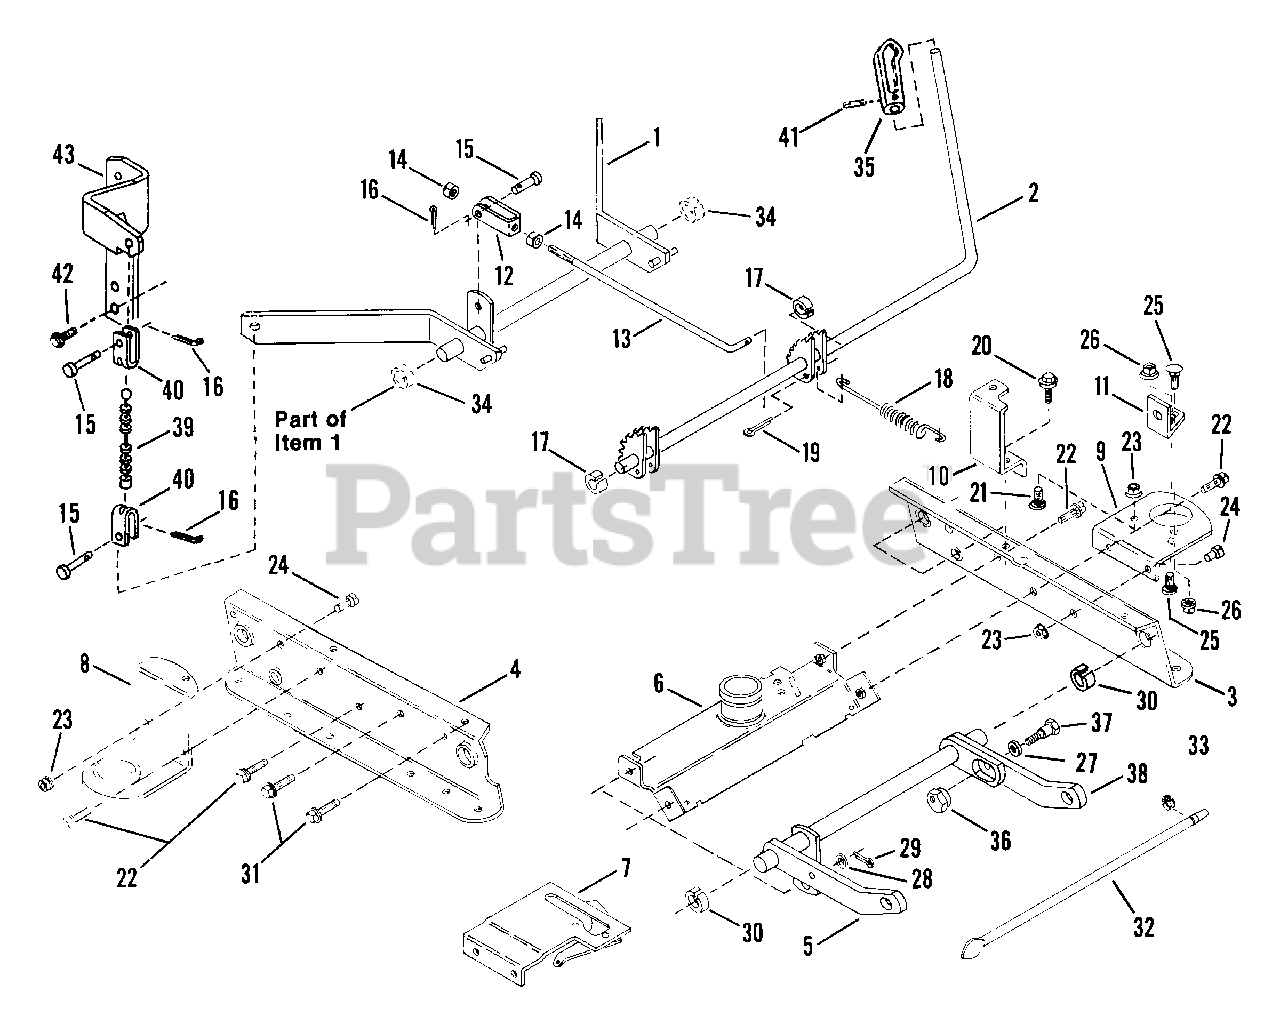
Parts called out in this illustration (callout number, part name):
1	ASSEMBLY, Rear Lift Arm
2	LEVER, Height Adjustment Lift
3	RAIL, Left Half
4	RAIL, Right Half
5	STRUCTURE, Front Lift Arm
6	BRACE, Weldment
7	ASSEMBLY, Clutch Plate
8	SPINDLE, Brace (Right)
9	SPINDLE, Brace (Left)
10	BRACKET, Cover
11	ANCHOR
12	CLEVIS, Timing Rod
13	ROD, Timing
14	NUT, 3/8-24 Hex
15	PIN, 3/8 x 1 1/16" Clevis
16	PIN, 3/32 x 3/4" Cotter
17	RING, Black
18	SPRING, Cam Lift
19	PIN, 5/32 x 1" Cotter
20	SCREW, 1/4-20 x 5/8" Self-Tap
21	SCREW, 3/8-24 x 1" Hex Cap
22	SCREW, 3/8-16 x 1" Self-Tap
23	NUT, 3/8-24 Hex Lock
24	SCREW, 3/8-24 x 3/4" Hex Cap
25	BOLT, 5/16-18 x 3/4" Carriage
26	NUT, 5/16-18 Hex Flange Lock
27	WASHER, 3/8 Internal Tooth Lock
28	WASHER, 3/8" Flat
29	PIN, 1/8 x 3/4" Cotter
30	RING, Red
31	SCREW, 5/16-18 x 5/8" Hex Self-Tapping
32	SUPPORT, Rod
33	RING, Retaining
34	RING, Blue
35	GRIP, Height Adjustment Lever
36	ECCENTRIC, Leveling
37	BOLT, 3/8-24 x 3/4" Shoulder
38	ARM, Front Lift (Left Side)
39	CABLE, 41" Deck
40	BRACKET, Cable
41	PIN, 3/16 x 3/4" Roll
42	SCREW, 5/16-18 x 1" Hex Self-Tapping
43	DECK-WING, Rear (Right)
